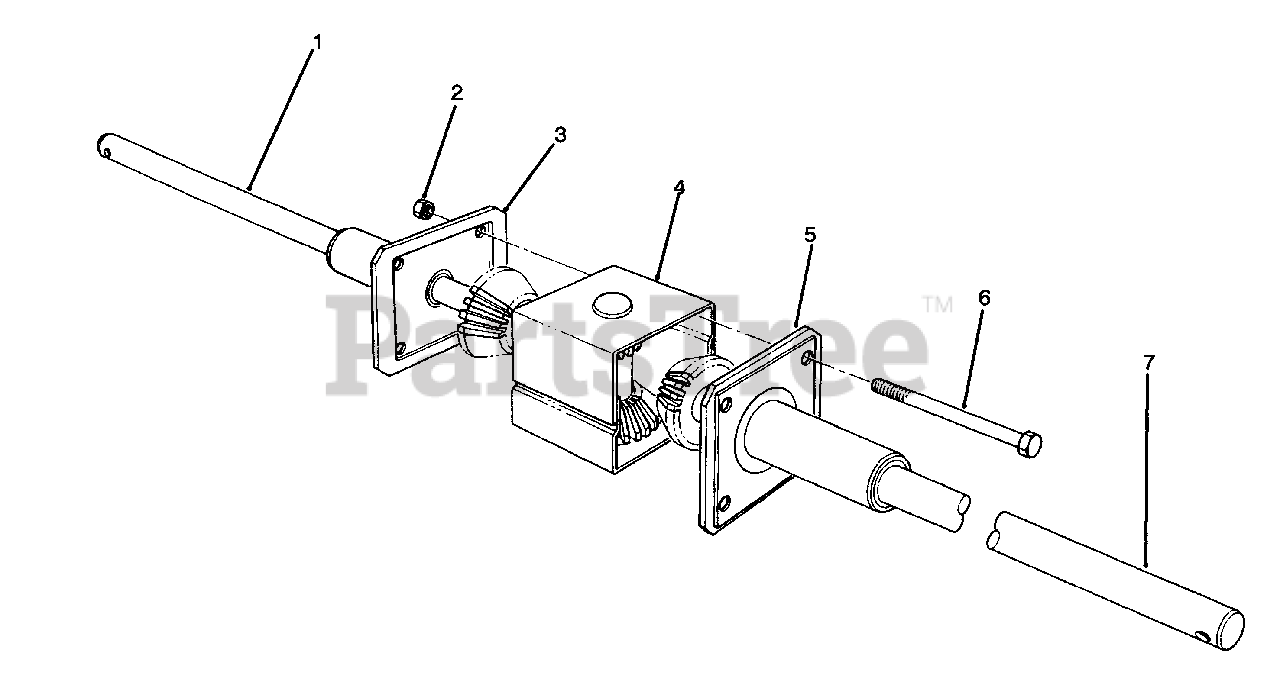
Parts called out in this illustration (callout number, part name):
1	Axle-R.H.
2	Nut-Lock
3	Cap-End, R.H.
4	Case-Gear, Transfer
5	Cap-End, L.H.
6	Screw-Cap Hex. Hd.
7	Axle-L.H.
